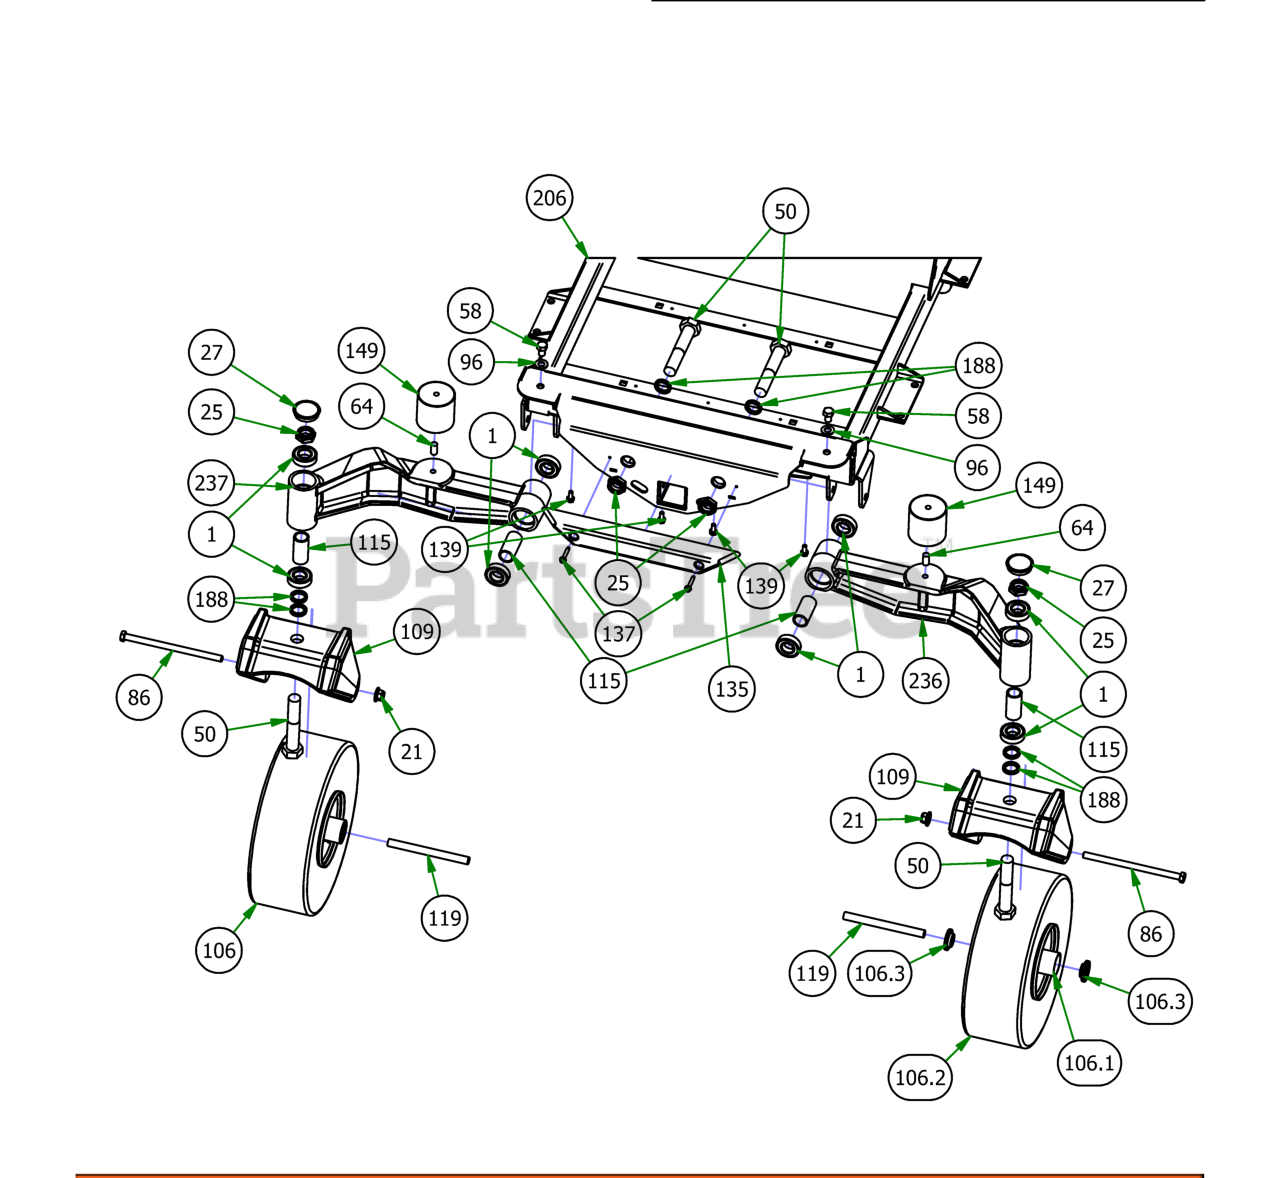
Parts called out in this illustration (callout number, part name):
1	1641 BEARING W/2 CONTACT RUBBER SEALS
21	1/2-13 NYLON INSERT FLANGE LOCKNUT ZINC
25	1" Fine Thread 1/2 Nylock Nut
27	2017 Bearing Cover
50	1-14 x 5.5 Hex Bolt Grade 8 Zinc Yellow
58	1/2" x 3/4" Hex Bolt
64	1/2-13 x 1" Stud
86	1/2" x 9" GR 5 Hex Bolt
96	1/2" Washer (Grade 8)
106	2019 15x6.00-6 Non Pneumatic Black Front Tire
106	2019 Front Tire Assy 15x6.00-6 pneumatic
106.1	6x4.5 Wheel w/Bearings
106.2	15x600-6 Tire Only
106.3	1-3/4" Bearing-Large Bore Front Rim
109	2020 R Series Cast Front Fork
115	2016 Front Bearing Spacer
119	Front Wheel Spanner
135	2017 XP Bumper
137	1/4" x 1 1/2" Self Tapping Screw
139	5/16 x 3/4 washer head type F screw
149	Vibration Mount-Blue Dot
188	Spacer, 1x1.375x.25
206	2019 Veritical Suspension Frame
236	2019 Front I-Beam Left
237	2019 Front I-Beam Right
